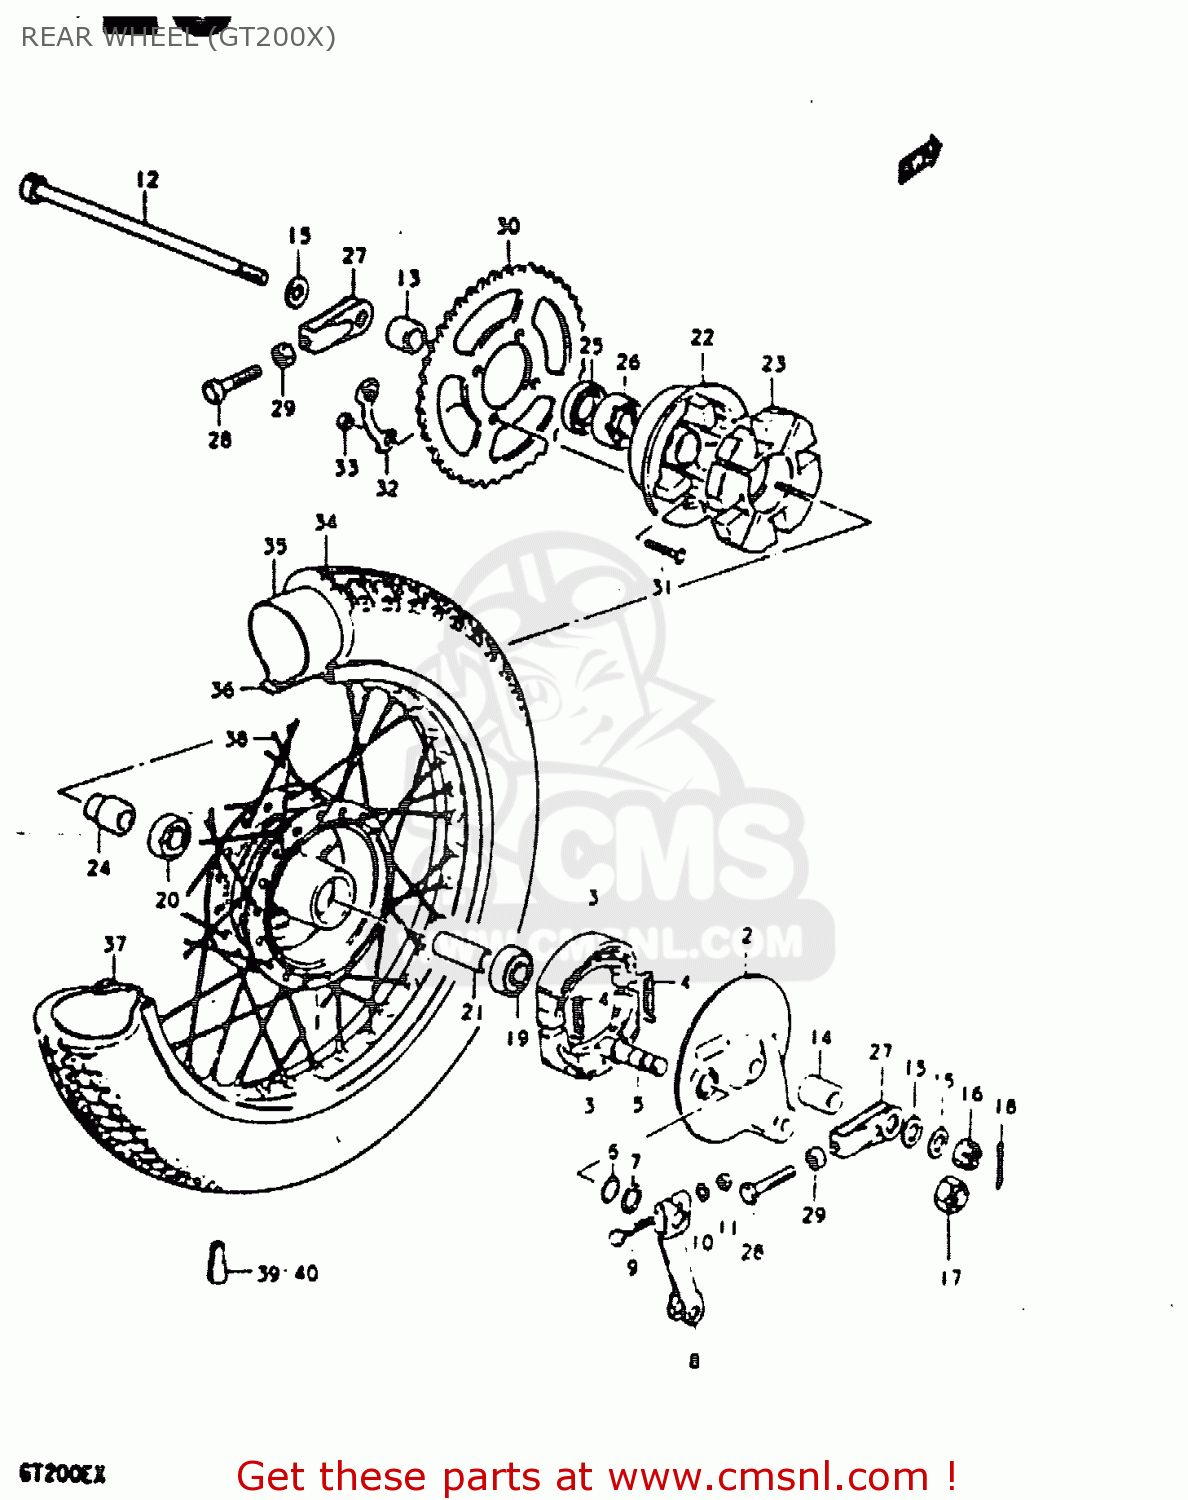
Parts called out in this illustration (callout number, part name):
1	HUB,REAR WHEEL
2	PANEL, REAR WHEEL
3	SHOE,BRAKE
4	SPRING(L:34)
5	CAM,FRONT BRAKE
6	O-RING (D:2.4 ID:13.8)
7	WASHER (14.5X22X1.6)
8	LEVER,RR BRAKE CAM
9	BOLT(6X33)
10	WASHER
11	NUT
12	AXLE,REAR
13	SPACER(15X28X19)
14	SPACER(15.2X26X33)
15	WASHER
16	NUT
18	COTTER PIN
19	BEARING
20	BEARING
21	SPACER(15.3X21.7X63)
22	DRUM,RR SPROCKET
23	ABSORBER ASSY,HUB SHOCK
24	RETAINER,RR SPROCKET MTG
25	SEAL,OIL(28X47X7)
26	Bearing
27	ADJUSTER,CHAIN
28	BOLT
29	NUT
30	SPROCKET,RR
31	BOLT(8X33.5)
32	WASHER
33	NUT
34	TIRE
35	TUBE,INNER
36	PROTECTOR,INNER TUBE
37	RIM, WHEEL
38	SPOKE SET
39	BALANCER,WHEEL (B)
40	BALANCER,WHEEL (30G)
